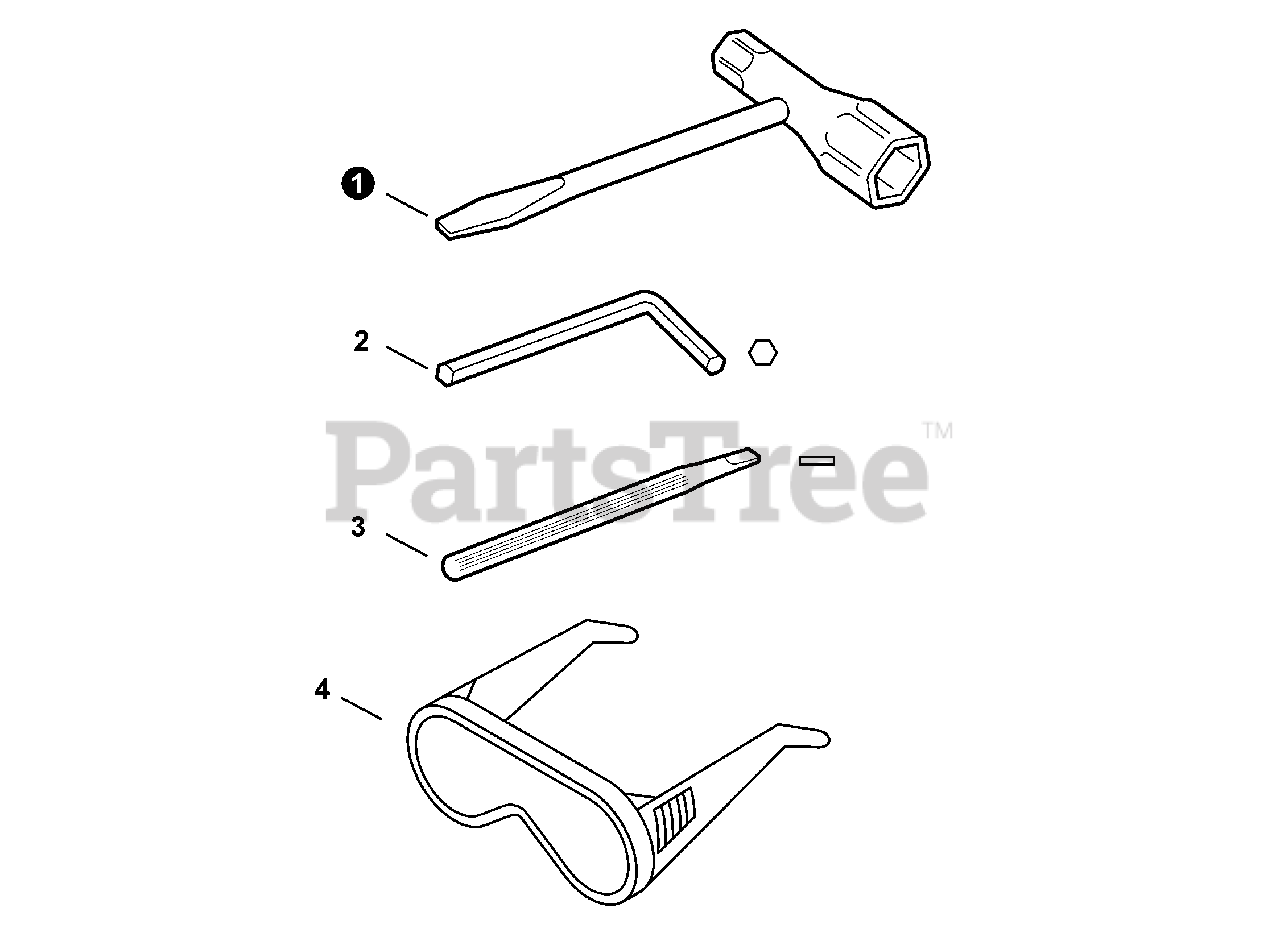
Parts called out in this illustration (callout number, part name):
1	T-WRENCH 13×19mm
2	WRENCH, ALLEN 4MM
3	SCREWDRIVER, PLASTIC
4	GLASSES, SAFETY
